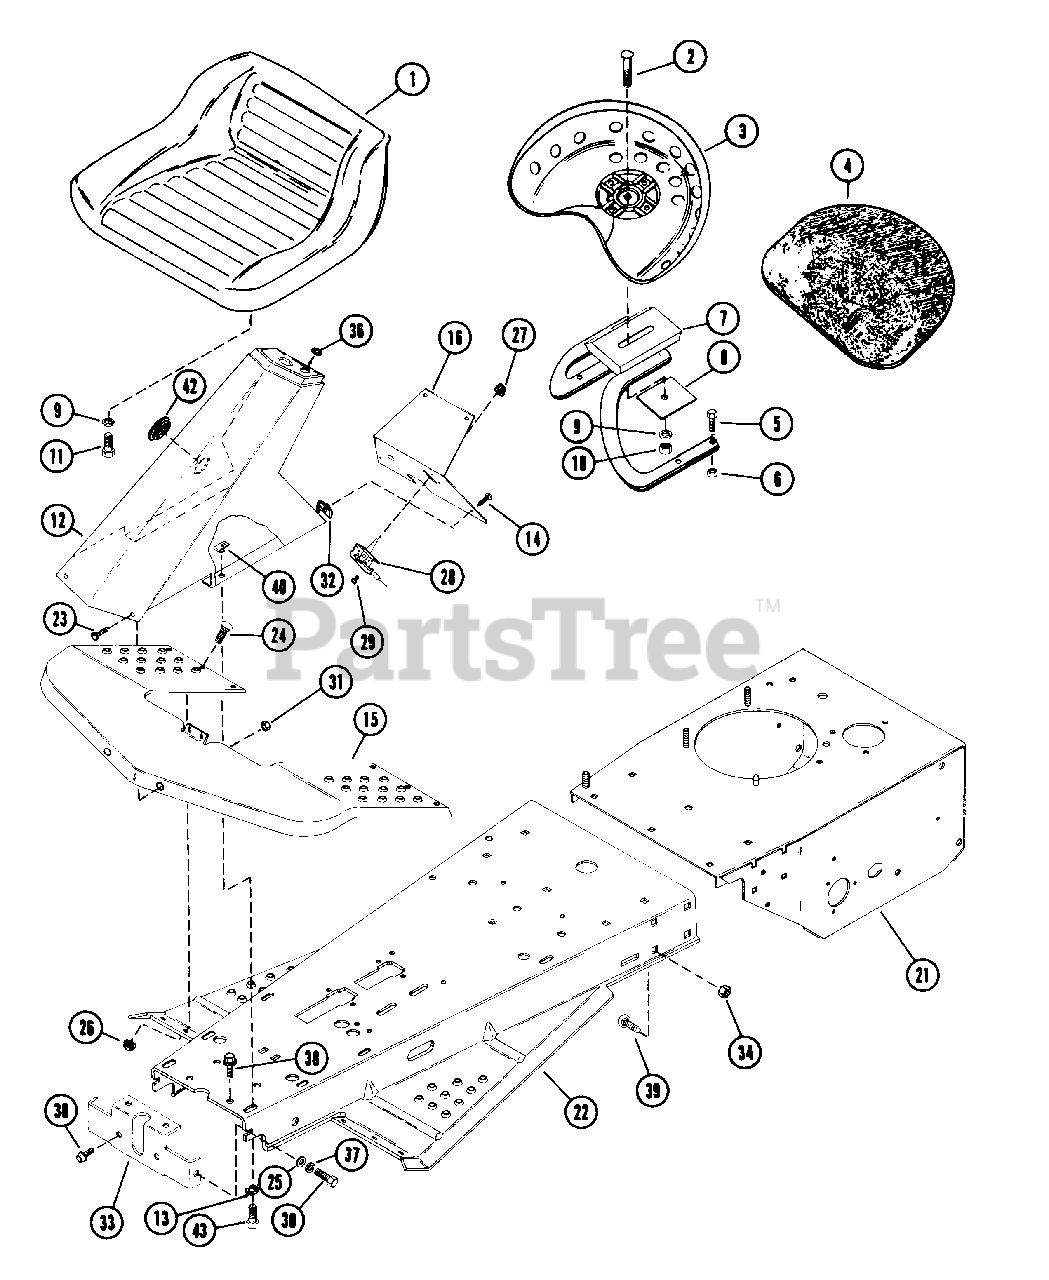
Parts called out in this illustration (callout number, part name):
1	SEAT
2	BLT-RDHDSQNK .50-13X1.25 PL
3	SEAT
4	SEAT COVER
5	BLT-HEX .31-18X1.50 PL GR2
6	NUT-LK .312-18 GR A PL
7	SEAT BRACKET
8	SEAT SUPPORT WASHER
9	WSHR-LK .500X.151 HVY PL
10	NUT .50-13 PL
11	BLT-HEX .50-13X1.25 PL GR2
12	STEERING COLUMN
13	WSHR-LK-INT .313X.030 PL
14	SCR-TAP 10-12X.50 CRPH PL A
15	FRONT FENDER
16	DASH PANEL ASSEMBLY
21	REAR FRAME
22	FRONT FRAME ASSEMBLY
23	SCR-MCH 10-24X.38 SLTOR PAN PL
24	SCR-SLTR-SERNK .25-20X.62 PL
25	WSHR-FL-STL .38X.875X.083 PL
26	NUT-LK-FLG .250-20 PL
28	THROTTLE CONTROL
29	RVT-POP.125 X .294 DOME
30	BLT-HEX .31-18X.75 PL GR2
31	NUT-LK TOP 10-24 PL
32	PLASTIC GROMMET
33	FRONT FRAME SUPPORT
34	NUT-FLG. .312-18 PL
36	GROMMET, .31 ID
37	WSHR-LK .312X.097 PL HVY
38	BLT-LK .31-18X.75 GR 5
39	BLT-RDHDSQNK .31-18X.75 GR5 PL
40	NUT-SPEED U-TY .312-18
43	BLT-HEX .31-18X.50 PL GR2
